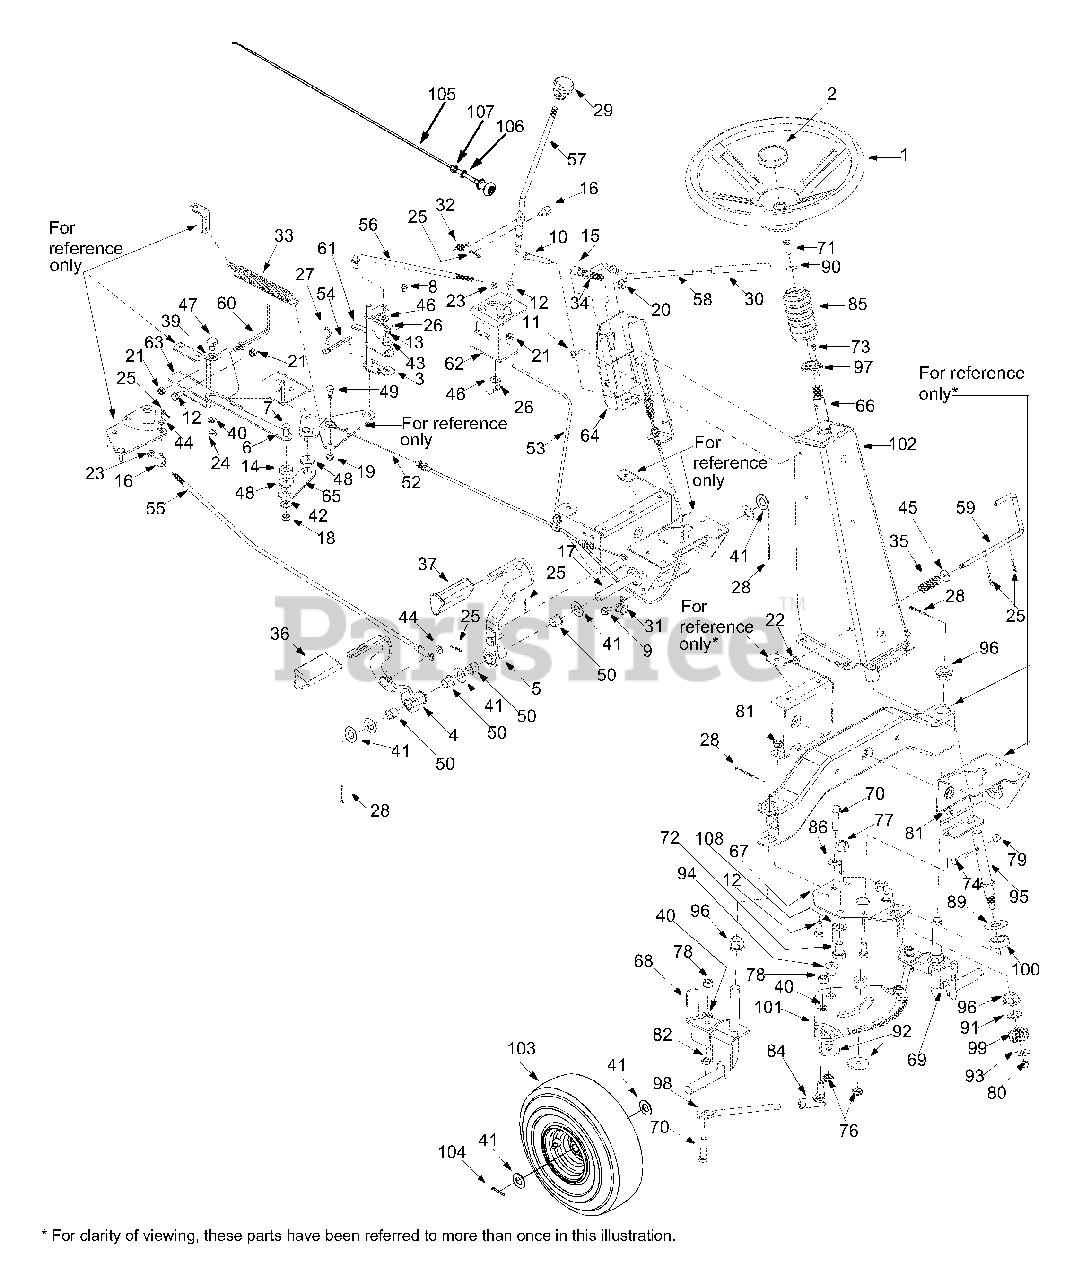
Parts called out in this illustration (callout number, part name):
1	Steering Wheel
2	Steering Wheel Cap
3	Shift Pivot Assembly
7	Hex Bolt 3/8-24 x 1.25"
8	TT Screw 1/4-20 x 0.5"
9	TT Screw 5/16-18 x 0.625"
10	Hex Bolt 3/8-16 x 2.5"
11	AB Screw 1/4-14 x 0.625"
12	Hex Bolt
13	Hex Bolt 1/4-20 x 0.50"
14	Spacer
15	Spacer
16	Ferrule
17	Shaft
18	Jam Nut 3/8-24
19	Flange Lock Nut 1/4-28
20	Flange Lock Nut 3/8-16
21	Nylon Lock Nut
22	Flange Lock Nut 5/16-18
23	Jam Nut 5/16-18
24	Hex Nut 3/8-16
25	Cotter Pin
26	Click Pin
27	Hairpin Clip
28	Cotter Pin
29	Shift Knob
30	Clutch Grip
31	Clamp
32	Extension Spring
33	Extension Spring
34	Compression Spring
35	Compression Spring
36	Drive Pad
37	Brake Pad
39	Flat Washer.53 x 1.0 x .032
40	Lock Washer 3/8
41	Flat Washer
42	Flat Washer
43	Bell Washer
44	Thrust Washer
45	Flat Washer
46	Flat Washer
47	Shoulder Screw .50 x .21: 3/8-16
48	Shoulder Spacer
49	Shoulder Screw 1/4-28 x .375
50	Flange Bearing
52	Deck Cable
53	Brake Cable
54	Shift Rod
55	Variable Control Rod
56	Control Rod
57	Shift Rod
58	PTO Lever
59	Brake Lock -Out Rod
60	Belt Keeper Rod
61	Shift Switch Bracket
62	Shift Index Bracket
63	Brake Mounting Bracket
64	Cont. Bracket: PTO
65	Link Bracket
68	Front Axle RH
69	Front Axle LH
70	Hex Bolt 3/8-24 x 1.5"
71	Hex Bolt 5/16-18 x 1.0"
72	Hex Bolt 1/2-13 x 0.75"
73	AB Screw #10-16 x 0.625"
74	Hex Bolt 1/4-20 x 1.25"
76	Jam Lock Nut 3/8-24
77	Hex Nut 1/2-13
78	Hex Nut 3/8-24
79	Hex Lock Nut 1/4-20
80	Hex Lock Nut 5/16-24
81	Hex Lock Nut
82	Jam Nut
84	Ball Joint 3/8-24
85	Steering Bellow
86	Bell Washer
89	Flat Washer.628 x 1.56 x .036
90	Bell Washer .340 x .872 x .060
91	Flat Washer .510 x 1.0 x .060
92	Flat Washer 3/8 x 1.37
93	Flat Washer .344 x 1.0 x .063
94	Spacer
95	Steering Adapter
96	Hex Flange Bearing
97	Bearing: Steering Column
98	Tie Rod
99	Pinion Gear
100	Spacer
101	Steering Gear
104	Cotter Pin
105	Choke Control
106	Lock Washer
107	Hex Nut, 3/8-16
108	Flat Washer, .53 x .93 x .050
